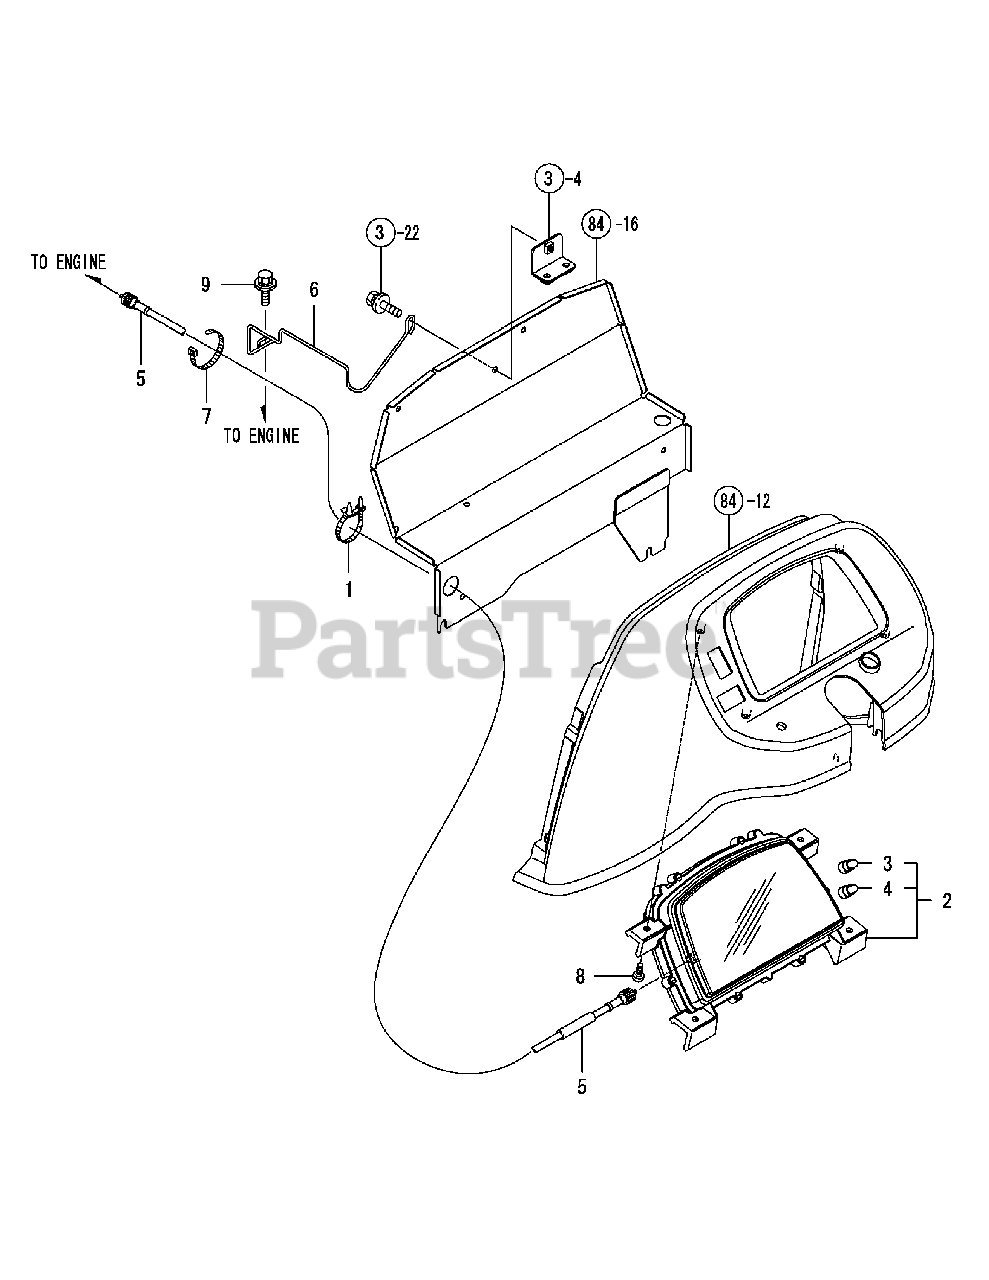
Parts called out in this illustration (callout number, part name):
2	Panel Assy, Instrument
4	Lamp 14V/1.4W,Socket
5	Cable, Hour Meter
7	Band 140,Wire Lock
